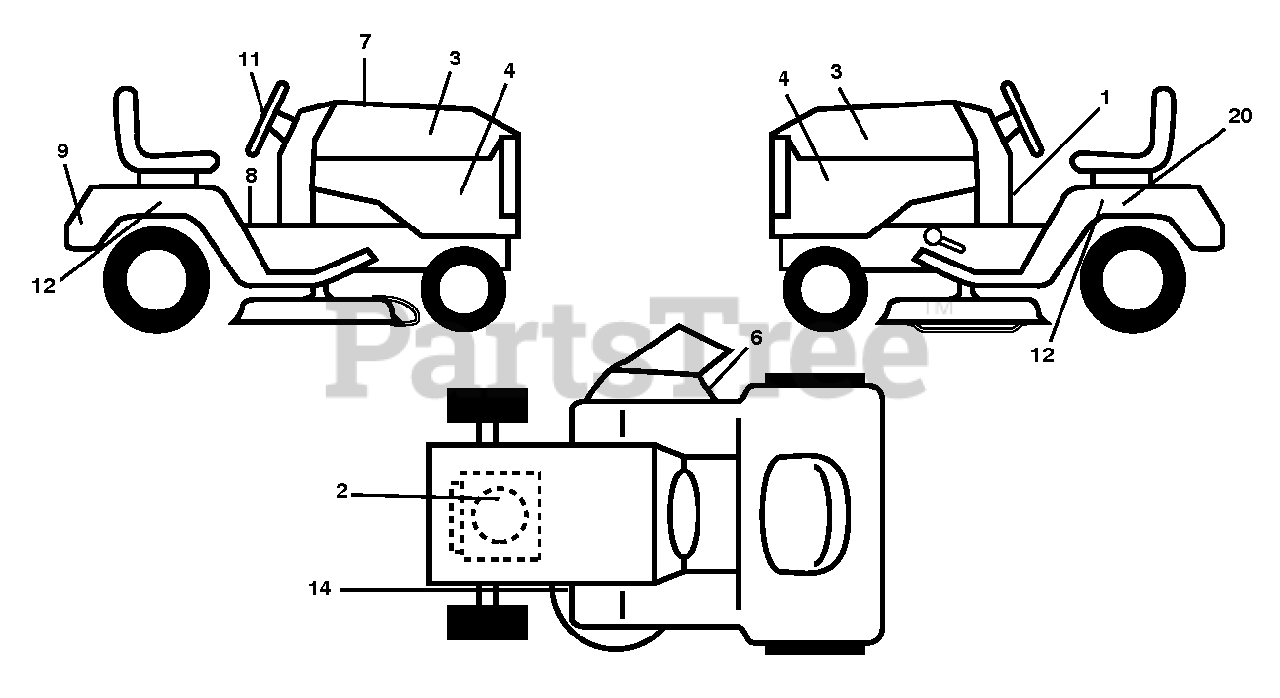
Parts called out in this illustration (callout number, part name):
1	DCL.WARNING.SPARK.IGNITION.CA
2	DECAL.ENG.BS.20HPXRD.SL.278416
3	DECAL.HOOD.POULAN.PRO.SET
6	DECAL.MOWER.WARN.KEEP.HAND.AWY
8	DECAL.WARNING.2007.ENG/FR
9	DECAL.REAR.FNDR.LOGO.POULAN.PR
11	DECAL.STEER.WHEEL.POULAN.PRO
14	DECAL.V-BELT.SCH.42/46"MEC/ELE
20	DECAL BTRY SYMBOLS
